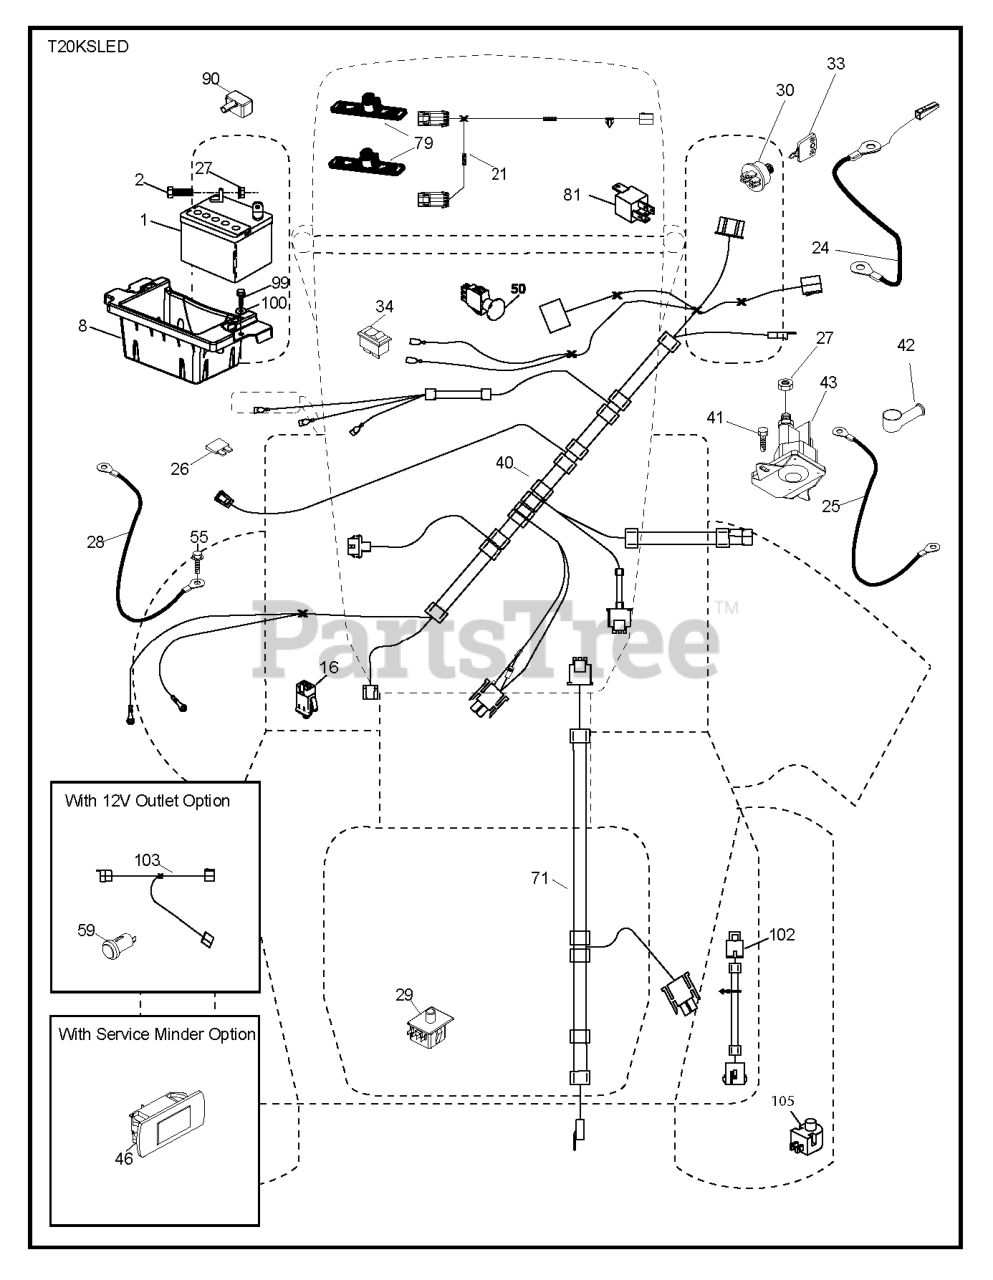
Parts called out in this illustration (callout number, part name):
1	Battery 12 Volt 25 Amp
2	BOLT.HEX.1/4.X.3/4.DICHROMATE
8	TRAY.BATTERY BOX.FRONT
16	SWITCH INTERLOOK PUSH-IN
24	CABLE.FRBATT.W/WIRE.8GA.8
25	CABLE.STARTER.8GA.17.5
26	FUSE 20AMP
28	CABLE.GROUND.21"BLK.8GA.90T
29	SWITCH.SEAT.DP W/RAMPS
30	SWITCH.IGN.DELTA.W.LGH.ROS
33	KEY.CHAIN.BLISTER.PACK.GEN.INT
40	HARNESS.IGN.ELEC.RELAY.TEX.46
41	SCREW
42	TERMINAL COVER
46	GUAGE.SRVCMNDR.HRMTR.
50	RP SWITCH.PTO.TERMINAL.STD.RED
55	SCREW 5/16"
71	HARNESS-CHASSIS SUB
81	RELAY HARNESS.SEALED
90	COVER.TERMINAL.BATTERY
99	SCREW HEXWSHR 1/4-20X3/4
102	HARNESS PIGTAIL PCH TEX ROS
105	REVERSE SWITCH
